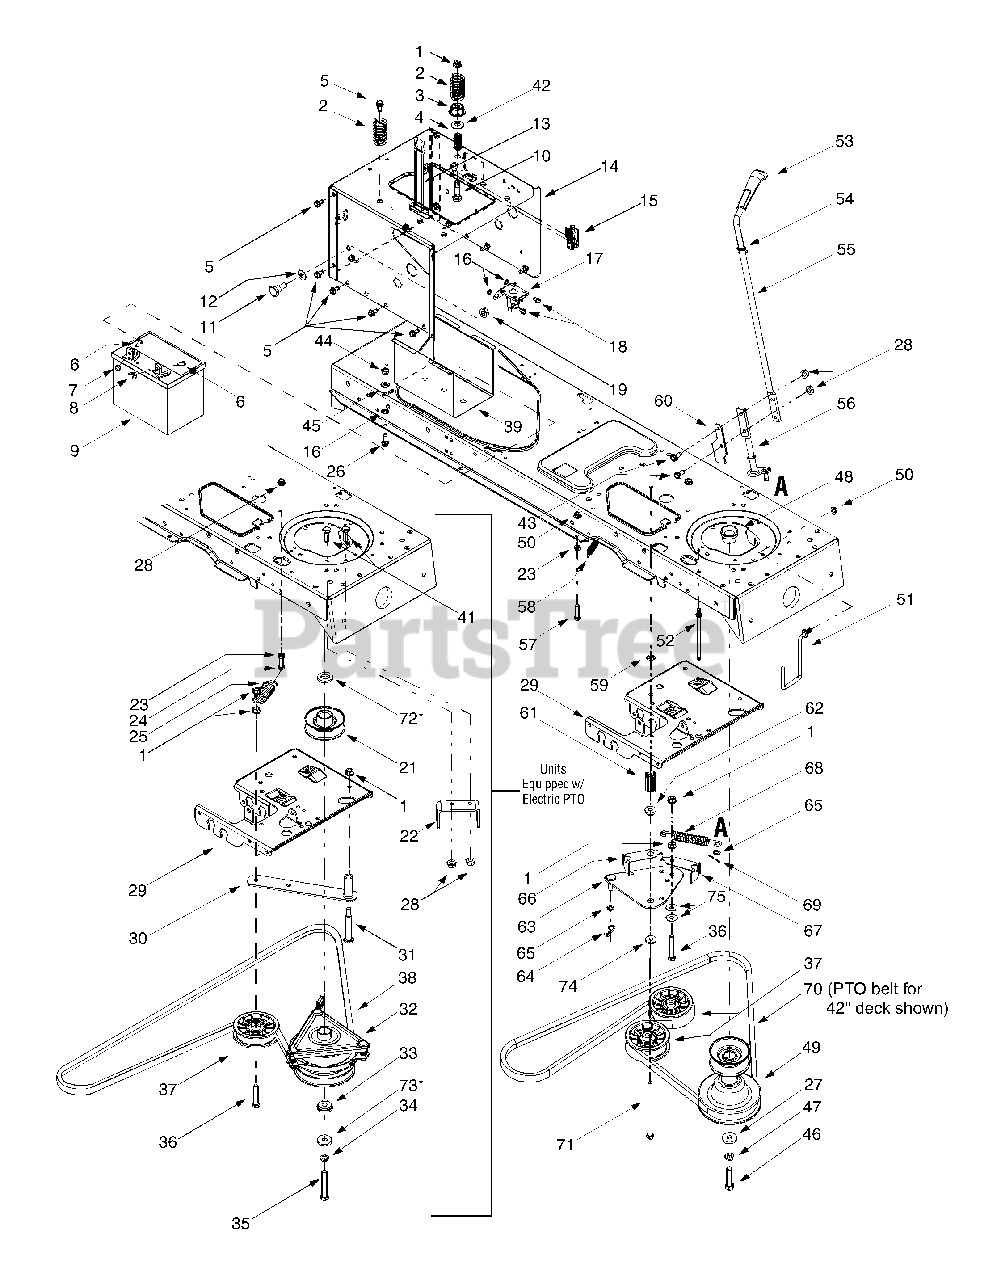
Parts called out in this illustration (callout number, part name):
1	Flange Lock Nut, 3/8-16
2	Compression Spring, 1.31 x 3.0
3	Spacer Cup, 1.5 OD
4	Compression Spring, .66 OD x 1.5
5	Self-Tapping Screw, 5/16-18 x .625
6	Hex Cap Screw, 1/4-20 x .62
7	Hex Sems Nut, 1/4-20
8	Wing Nut, 1/4-20
9	12-Volt Battery, 270 CCA
10	Shoulder Screw, .5 x 1.25, 3/8-16
11	Shoulder Screw, .625 x .5, 7/16-20
12	Bell Washer, .45 x 1.0 x .062
13	Battery Strap
16	Lock Washer, 1/4
17	Solenoid, 12-Volt, 100 Amp
18	Self-tapping Screw, 1/4-20 x .5
19	Flange Lock Nut, 7/16-20
24	Hex Cap Screw, 5/16-18 x 1.75
25	Extension Spring, 1.2 OD x 3.638
26	Self-tapping Screw, 1/4-20 x .750
27	Flat Washer, .45 x 1.25 x .164
28	Flange Lock Nut, 5/16-18
32	Electric PTO Clutch
33	Shoulder Spacer, 1.38 x .445 x .36
34	Lock Washer, 7/16
35	Hex Cap Screw, 7/16-20 x 3.25
36	Hex Cap Screw, 3/8-16 x 2.25
37	Flat Idler Pulley, 3.5 OD
38	PTO Belt
41	Hex Cap Screw, 5/16-18 x .625
42	Bell Washer, .401 x .870 x .063
43	Hex Cap Screw, 5/16-18 x 1.0
44	Hex Nut, 1/4-20
45	Lock Washer, 5/16
46	Hex Cap Screw, 7/16-20 x 1.5
47	Lock Washer, 7/16
48	Spacer
49	Engine Pulley
50	Flange Lock Nut, 5/16-18
51	Belt Guard
52	Keeper Pin
53	PTO Knob
54	Flat Washer, .510 x .750 x .033
55	PTO Handle
56	PTO Lever
57	Hex Cap Screw, 5/16-18 x 1.25
58	Extension Spring, .5 x 6.0
59	Push Nut, 3/8
61	Spacer, 3/8 x 1.54
62	Shoulder Spacer
64	Internal Cotter Pin
65	Flat Washer, .385 x .62 x .063
66	Belt Guard
67	Belt Guard
68	Extension Spring, .75 x 6.75
69	Cotter Pin, 3/32 x 1.0
70	PTO Belt
71	Hex Cap Screw, 3/8-16 x 5.0
72	Flat Washer, 1.031 x 1.62 x .095
73	Flat Washer, .45 x 1.25 x .17
74	Flat Washer. 3/8 x .87 x .06
75	Flat Washer, .395 x 1.12 x .10
